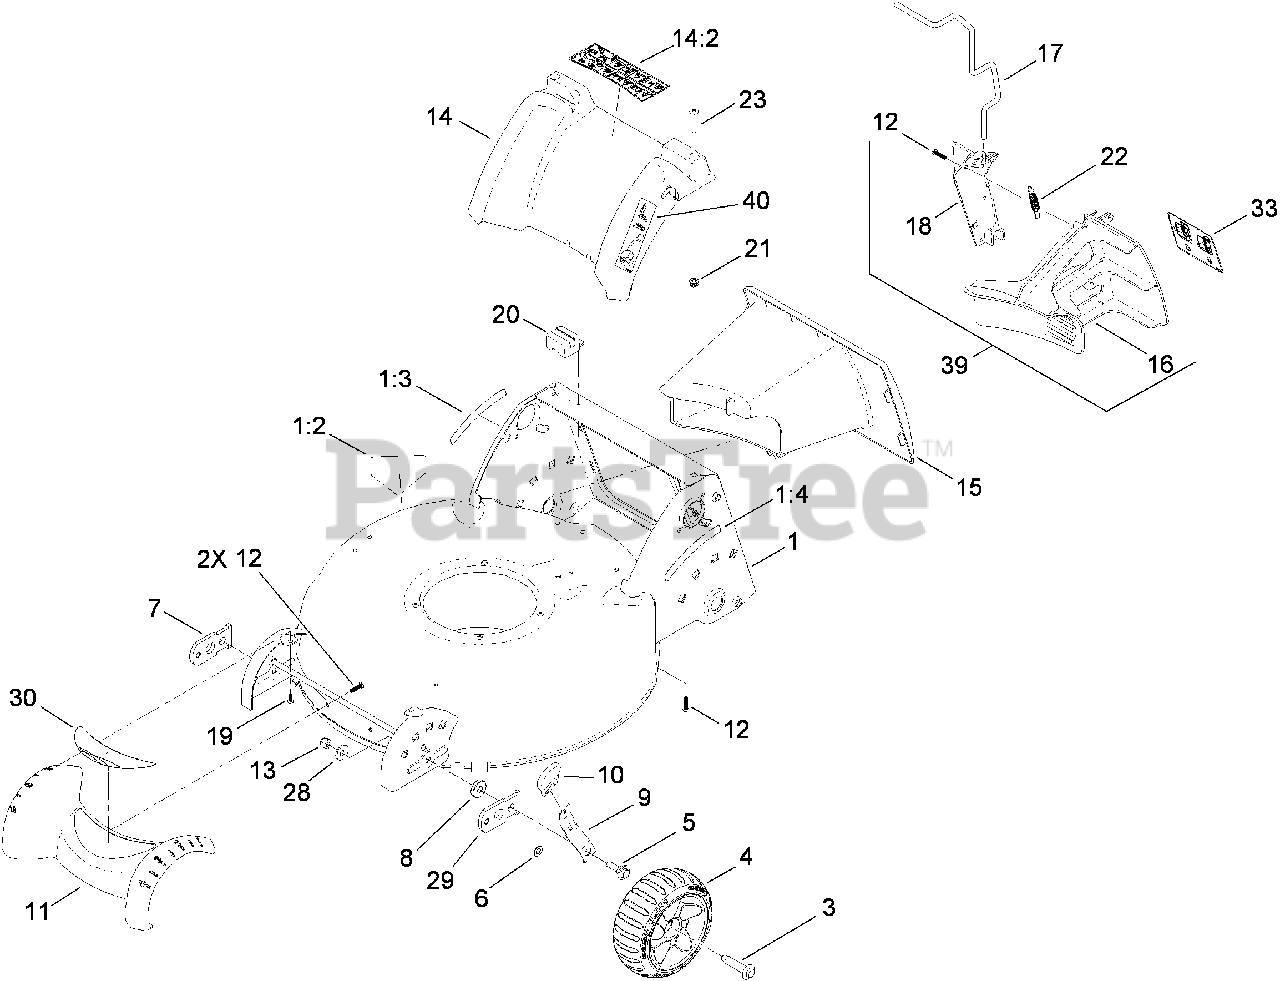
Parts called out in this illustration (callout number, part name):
1	53 CM DECK BAFFLE ASM
1:2	DECAL-DANGER
1:3	DECAL-HOC, RH
1:4	DECAL-HOC, LH
3	BOLT-SHOULDER
4	7 INCH FRONT WHEEL ASM
5	BOLT-SHOULDER
7	ARM-PIVOT, RH
9	ARM-SPRING
11	COVER-FRONT
12	SCREW-PLASTITE
13	NUT-LOCK, NI
14	COVER-REAR
14:2	DECAL-WARNING
16	PLUG-MULCH, LH
17	LATCH-PLUG, MULCH
18	PLUG-MULCH, RH
19	SCREW-PLASTITE
20	MODULE-SWITCH
21	NUT-CLIP
22	SPRING-EXTENSION
23	SCREW-PTH
28	WASHER-HARDENED
29	ARM-PIVOT, LH
33	DECAL-PLUG, MULCH
39	MULCH PLUG ASM
40	DECAL
